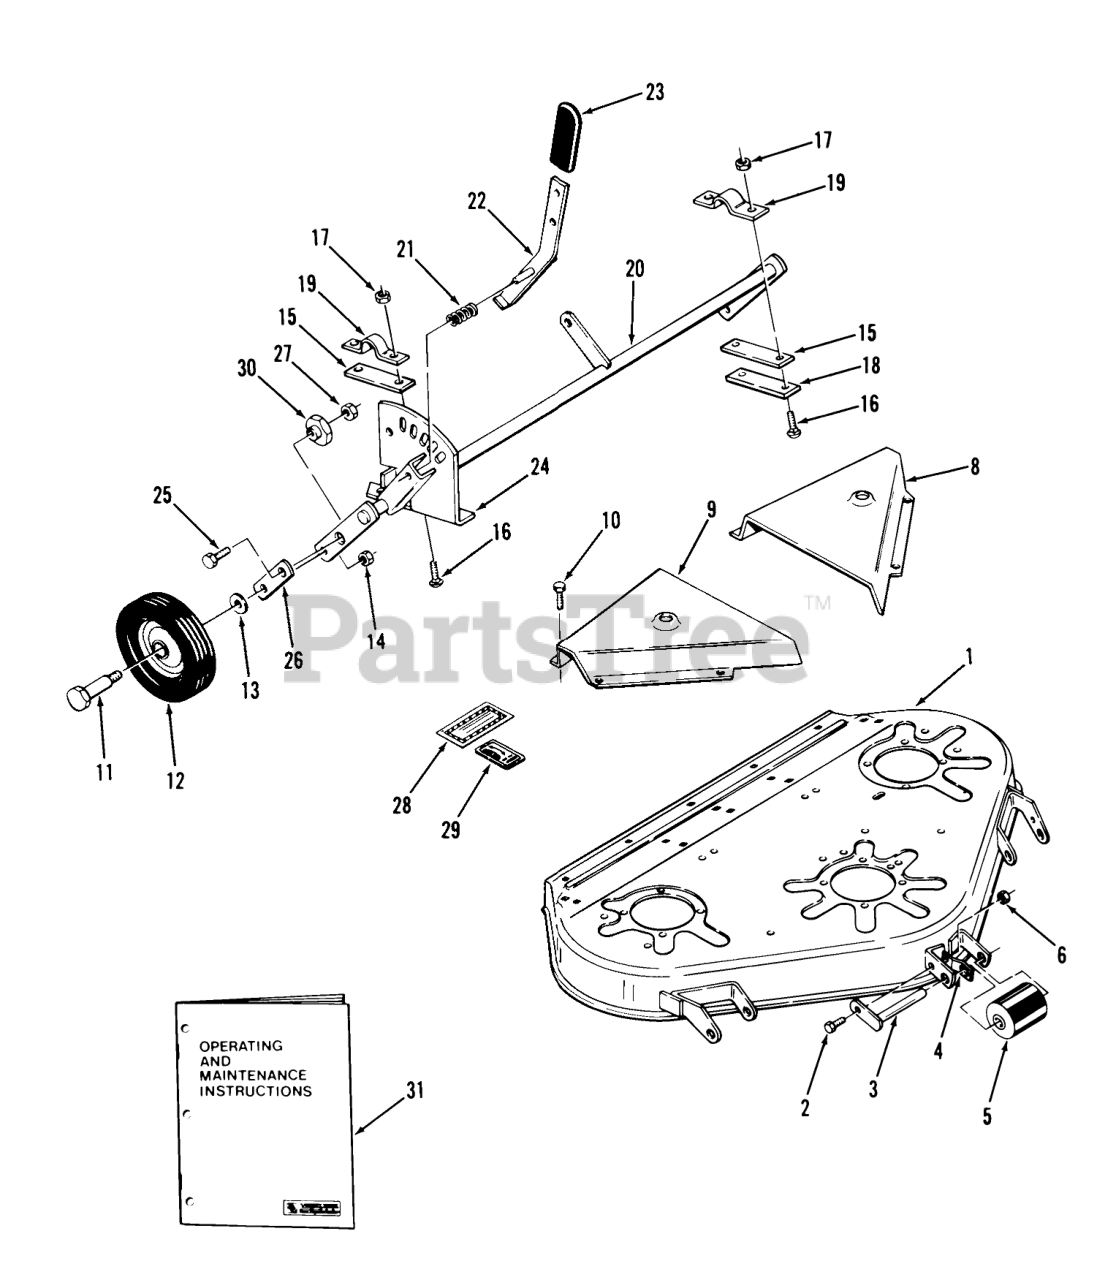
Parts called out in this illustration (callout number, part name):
1	Mower Deck Assembly
2	H H C S
3	Roller Shaft
4	SPRING ROLLER STOP
5	Roller
6	Nut
8	Belt Cover LH
9	Belt Cover RH
10	Bolt
11	BOLT-SHOULDER
12	Wheel
13	WASHER
14	Nut
15	Strap 1/16
16	Bolt
17	Nut
18	Strap
19	CLAMP
20	Gage Wheel Support
21	SPRING-COMPRESSION
22	Lever
24	Quadrant
25	Bolt
26	Wheel Plate
27	Nut
28	Caution Decal
29	Decal, Height
30	STEERING ARM
31	Operating and Maintenance Instructions
